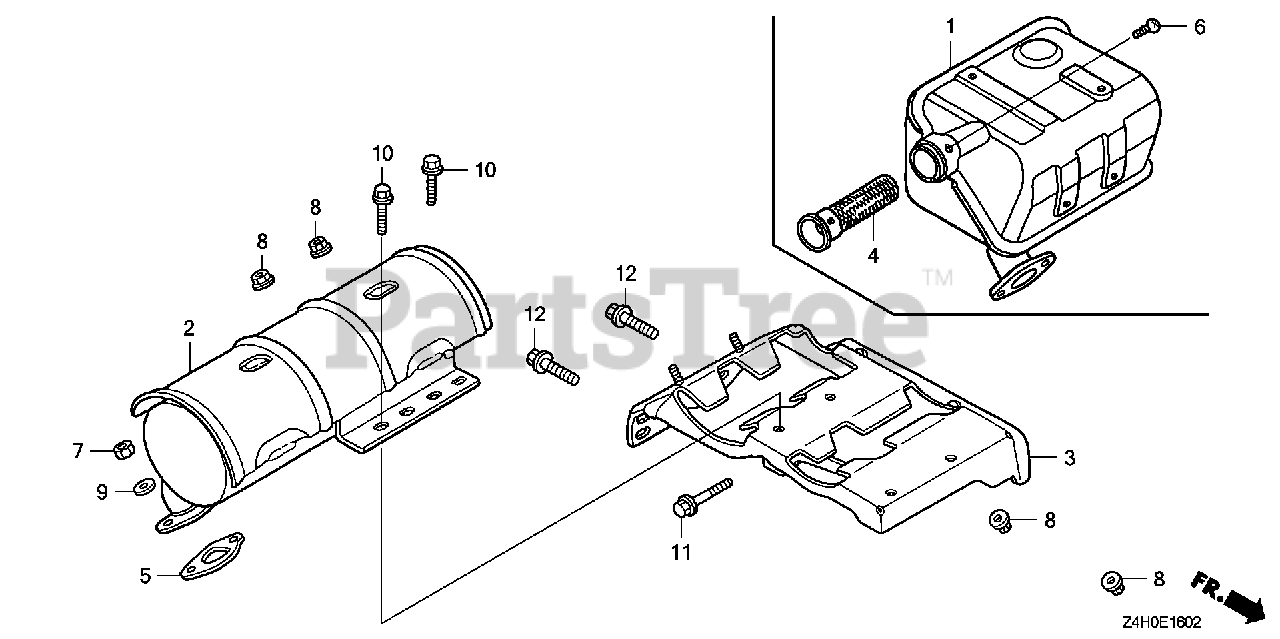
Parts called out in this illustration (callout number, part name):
1	MUFFLER (ARRESTER)
3	STAY, MUFFLER
4	ARRESTER, SPARK
5	GASKET, MUFFLER
6	SCREW, TAPPING (4X6) (TO INSTALL OPTIONAL SPARK ARRESTER)
7	NUT, HEX. (8MM)
8	NUT, FLANGE (6MM)
9	WASHER, PLAIN (8MM)
10	BOLT, FLANGE (6X16) Use from Engine SN 2056820.
11	BOLT, FLANGE (6X25)
12	BOLT, FLANGE (8X20) Use up to Engine SN 1609606.
